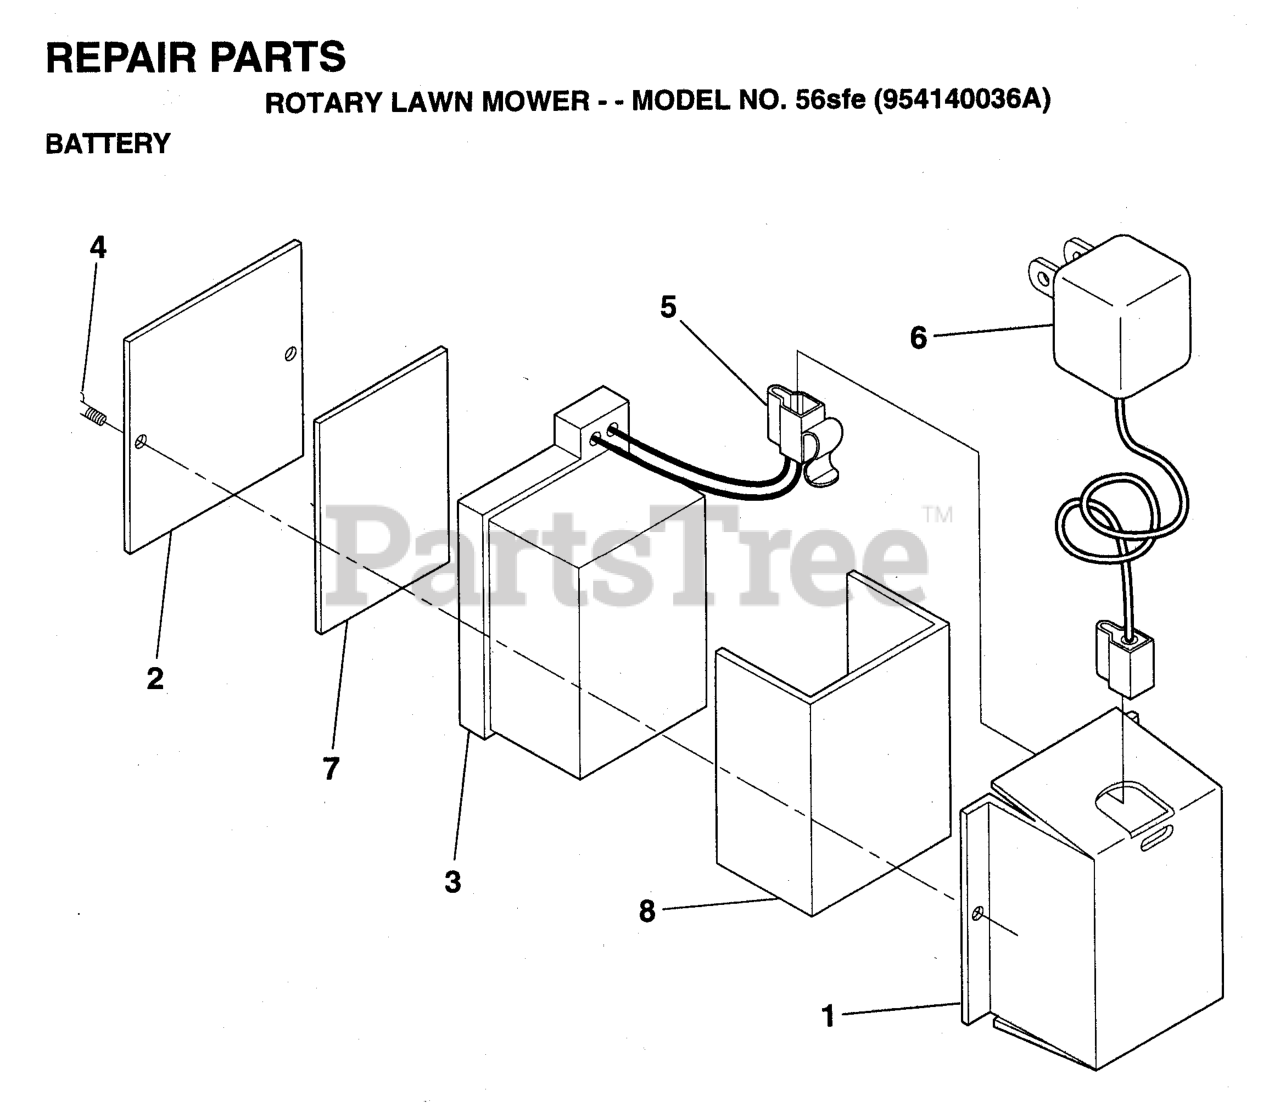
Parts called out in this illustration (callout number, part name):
1	BATTERY BRACKET
2	BATTERY COVER
3	KIT BATTERY REPL
4	TAPPING SCREW
5	CONNECTOR PM
6	KIT.CHARGER.BATTERY.
7	BATTERY PAD PM
8	BATTERY WRAP
